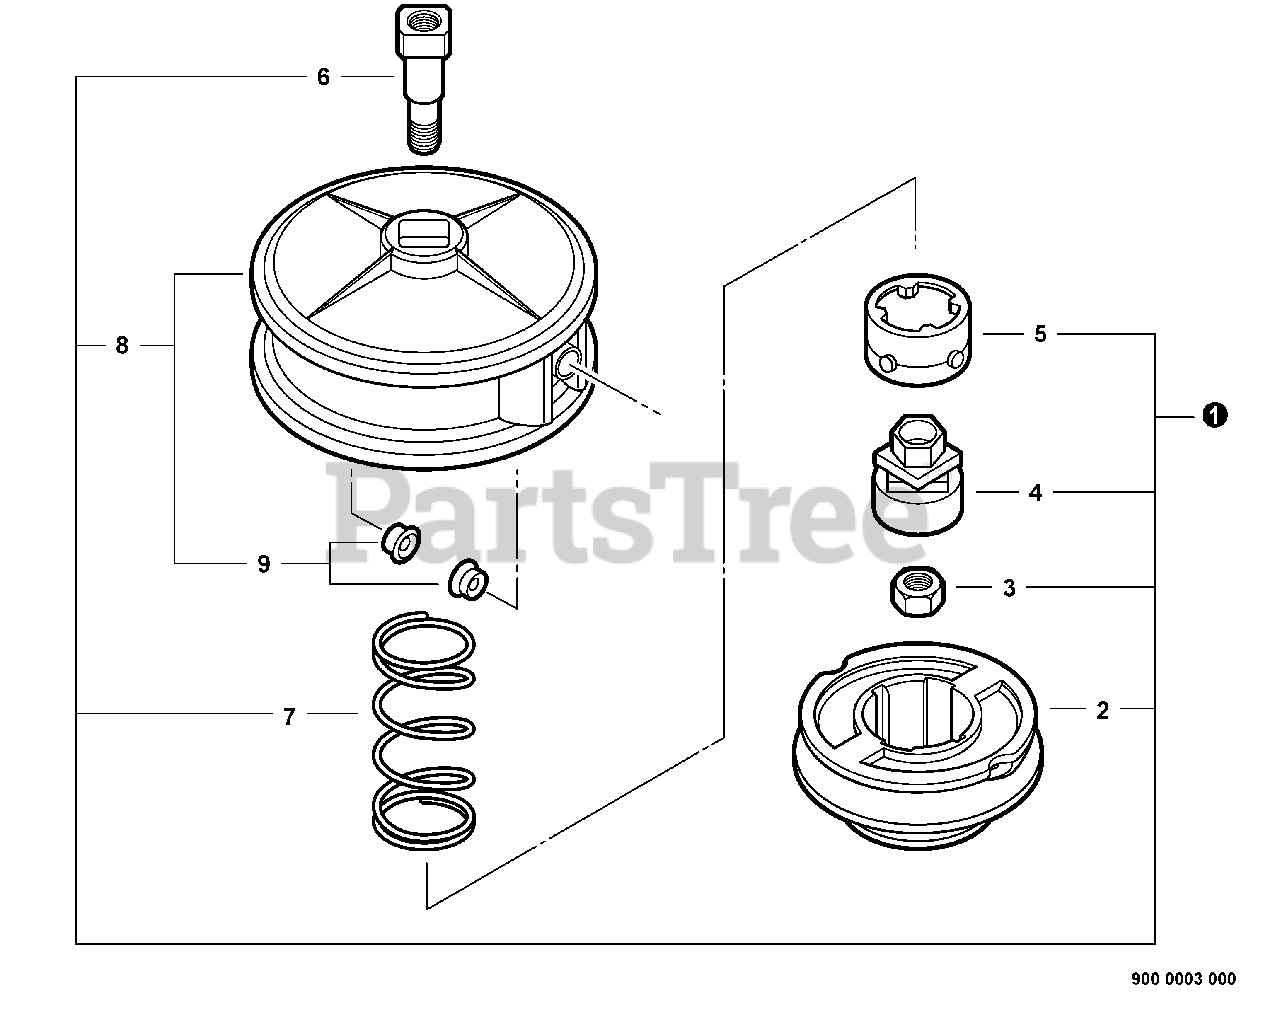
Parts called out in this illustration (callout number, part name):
1	U-TURN HEAD
4	CAM - INNER
5	DRIVE - OUTER
6	BOLT, SHAFT
8	SPOOL COVER ASSY
9	EYELET
